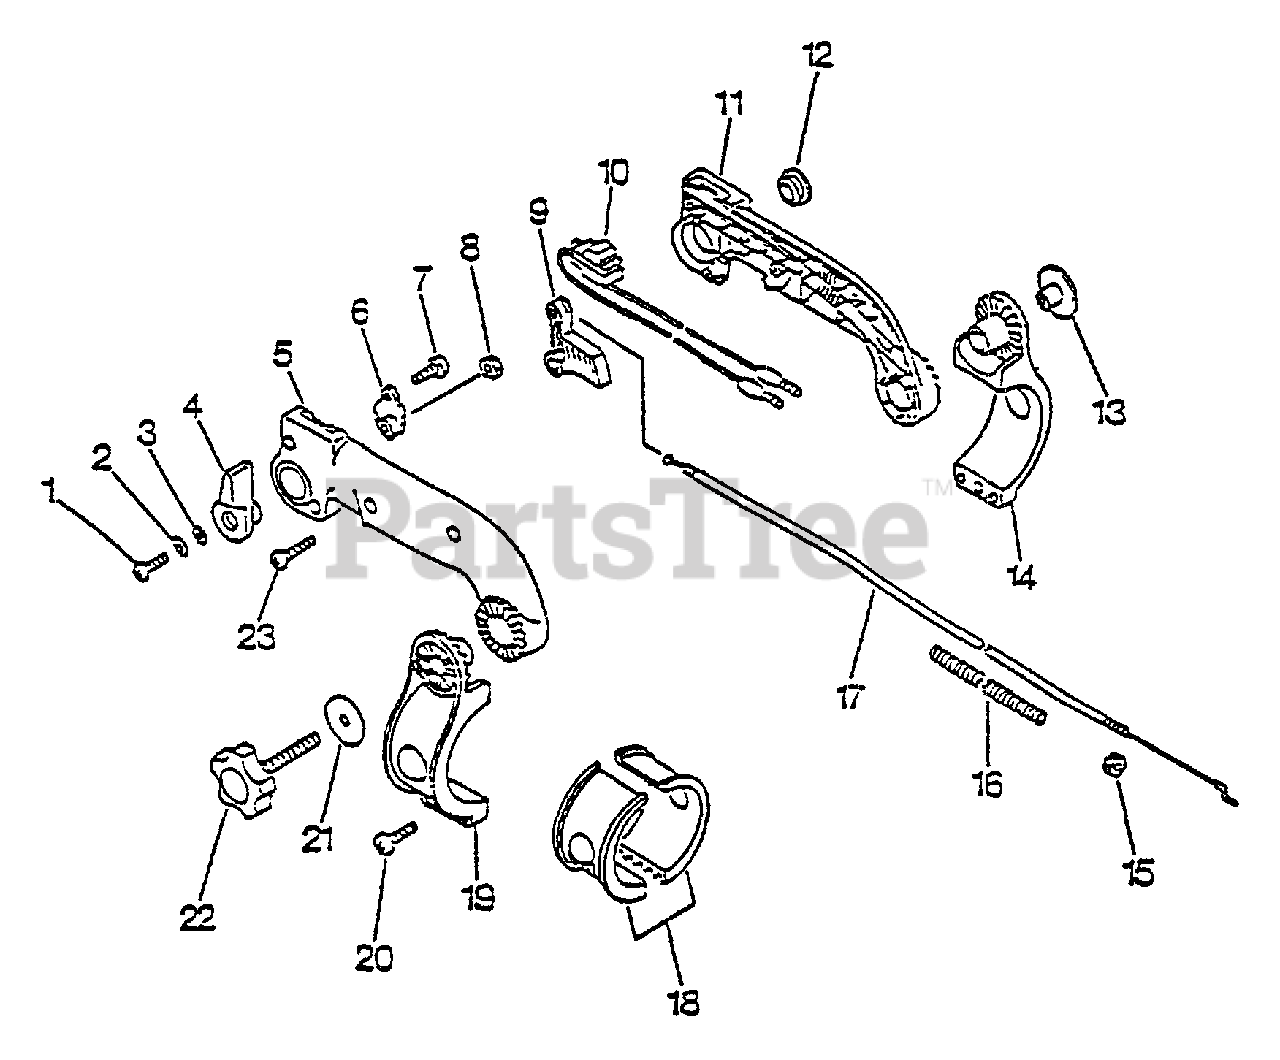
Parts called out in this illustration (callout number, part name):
1	SCREW 6×20
2	WASHER, SPRING 6
3	WASHER 6.5×13×1
4	TRIGGER, THROTTLE
5	CONTROL HANDLE - LEFT
6	BRACKET, THROTTLE
7	SCREW 4×10
8	NUT, HEX M6
9	TRIGGER, THROTTLE
10	IGNITION SWITCH ASSY
11	CONTROL HANDLE - RIGHT
14	BRACKET, HANDLE - RIGHT
15	NUT, HEX M6
16	TUBE, PROTECTIVE - CORRUGATED
17	CABLE, THROTTLE
19	BRACKET, HANDLE - LEFT
20	SCREW, TAPPING 5×20
22	THUMBSCREW
23	SCREW 4×22
